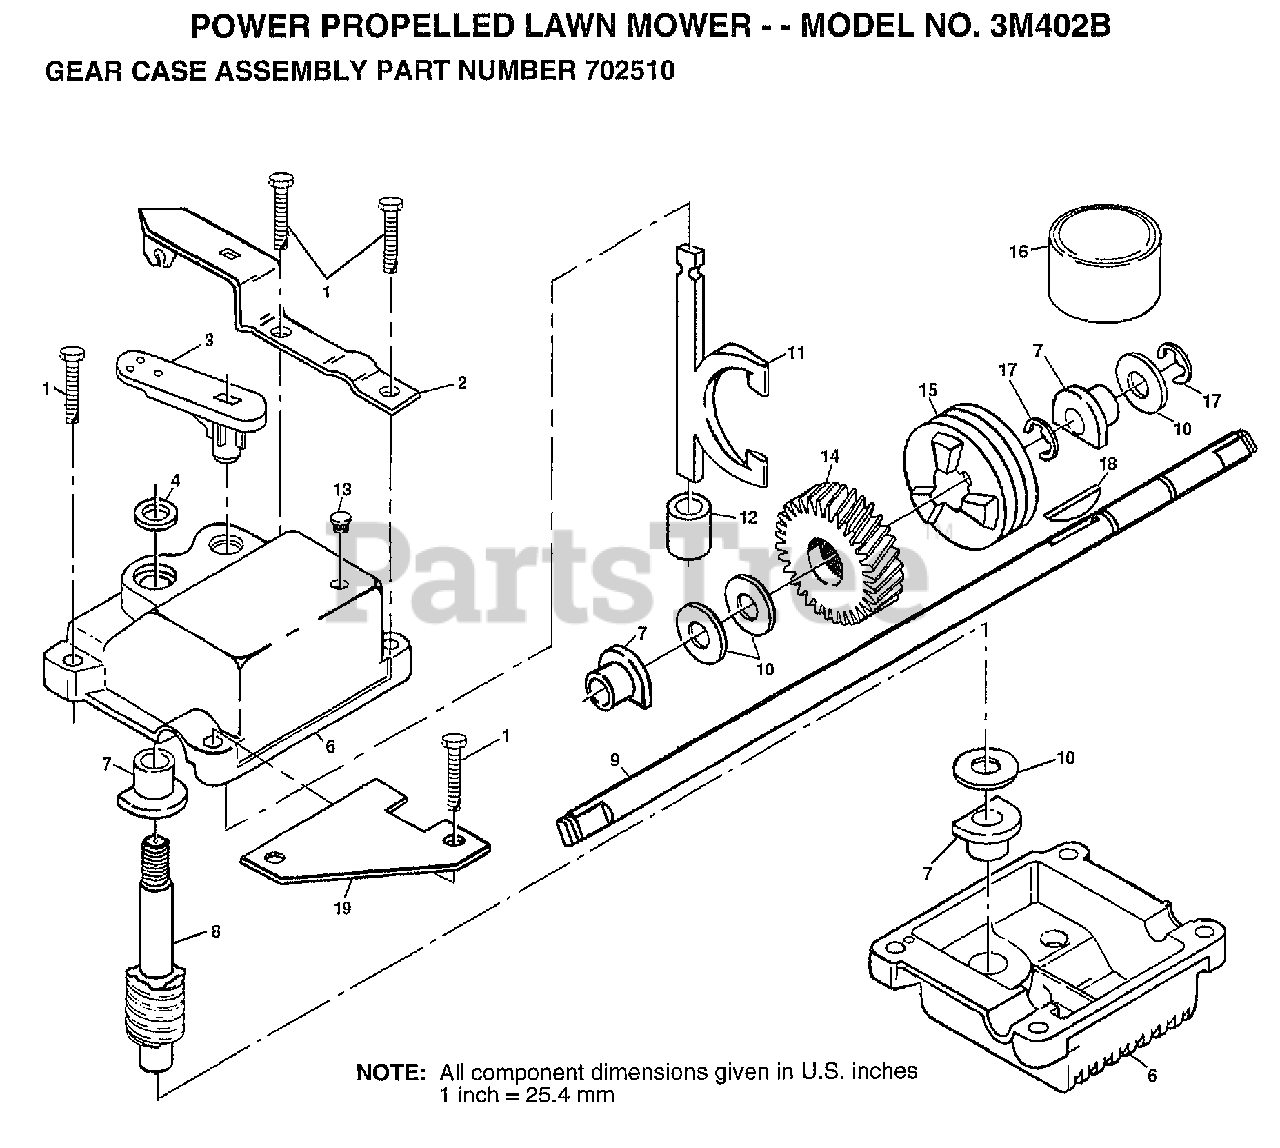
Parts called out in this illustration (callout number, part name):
1	SCREW.1/4-20
2	BRACKET.GEARCASE
3	SHIFTER
4	SEAL
6	KIT GEARCASE HALV
7	BEARING
8	SHAFT.WORM
9	SHAFT.DRIVE.SD
10	THRUST WASHER
11	CLUTCH YOKE
12	BUSHING.GEAR BOX
13	PLUG PM
14	GEAR.HELICAL
15	CLUTCH JAW
17	RING T
18	HI PRO KEY
